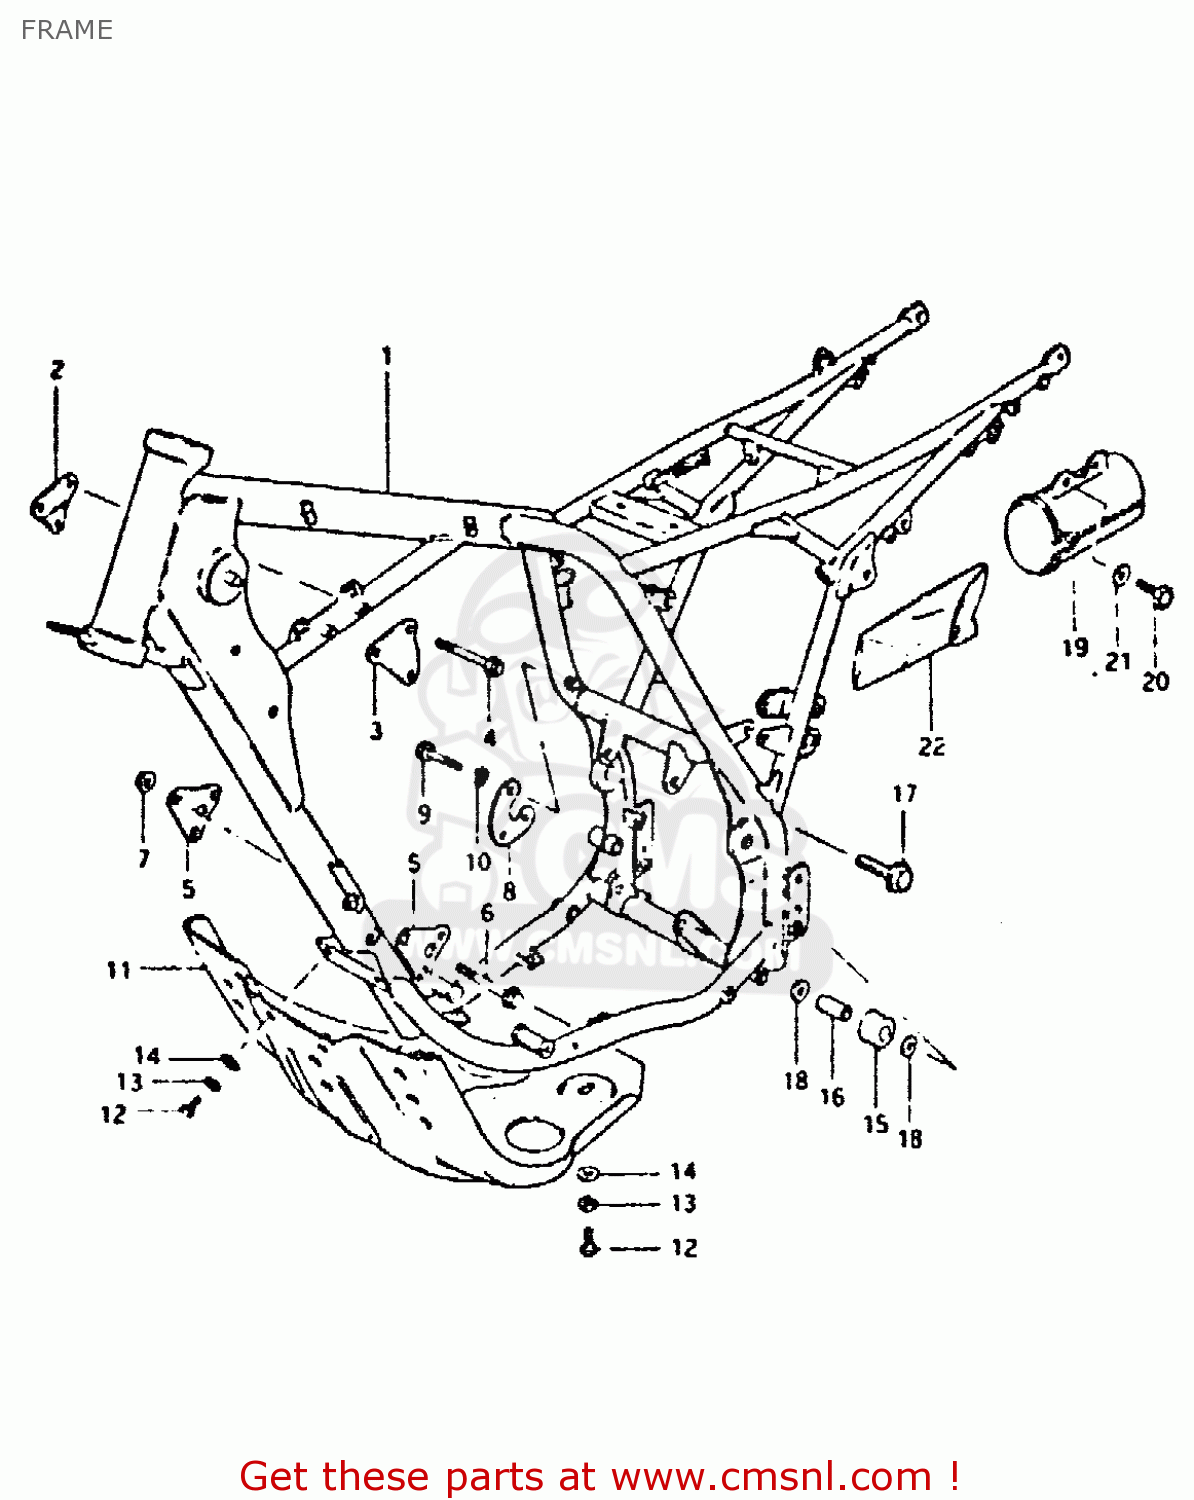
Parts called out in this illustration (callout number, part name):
1	FRAME (BLACK)
2	PLATE,ENGINE MOUNTING
3	PLATE,ENGINE MOUNTING
4	BOLT,UNDER
5	PLATE,ENGINE MOUNTING
6	BOLT(8X67)
7	NUT
8	PLATE,ENGINE MOUNTING
9	BOLT 8X55
10	LOCK WASHER
11	PROTECTOR,ENGINE
12	BOLT, UPPER
13	LOCK WASHER
14	WASHER 6MM
15	ROLLER,CHAIN LENGTH CONTROL
16	SPACER,CHAIN LENGTH ROLLER
17	BOLT(8X45)
18	WASHER
19	HOLDER,TOOL
20	BOLT, UPPER
21	WASHER
22	TOOL SET
